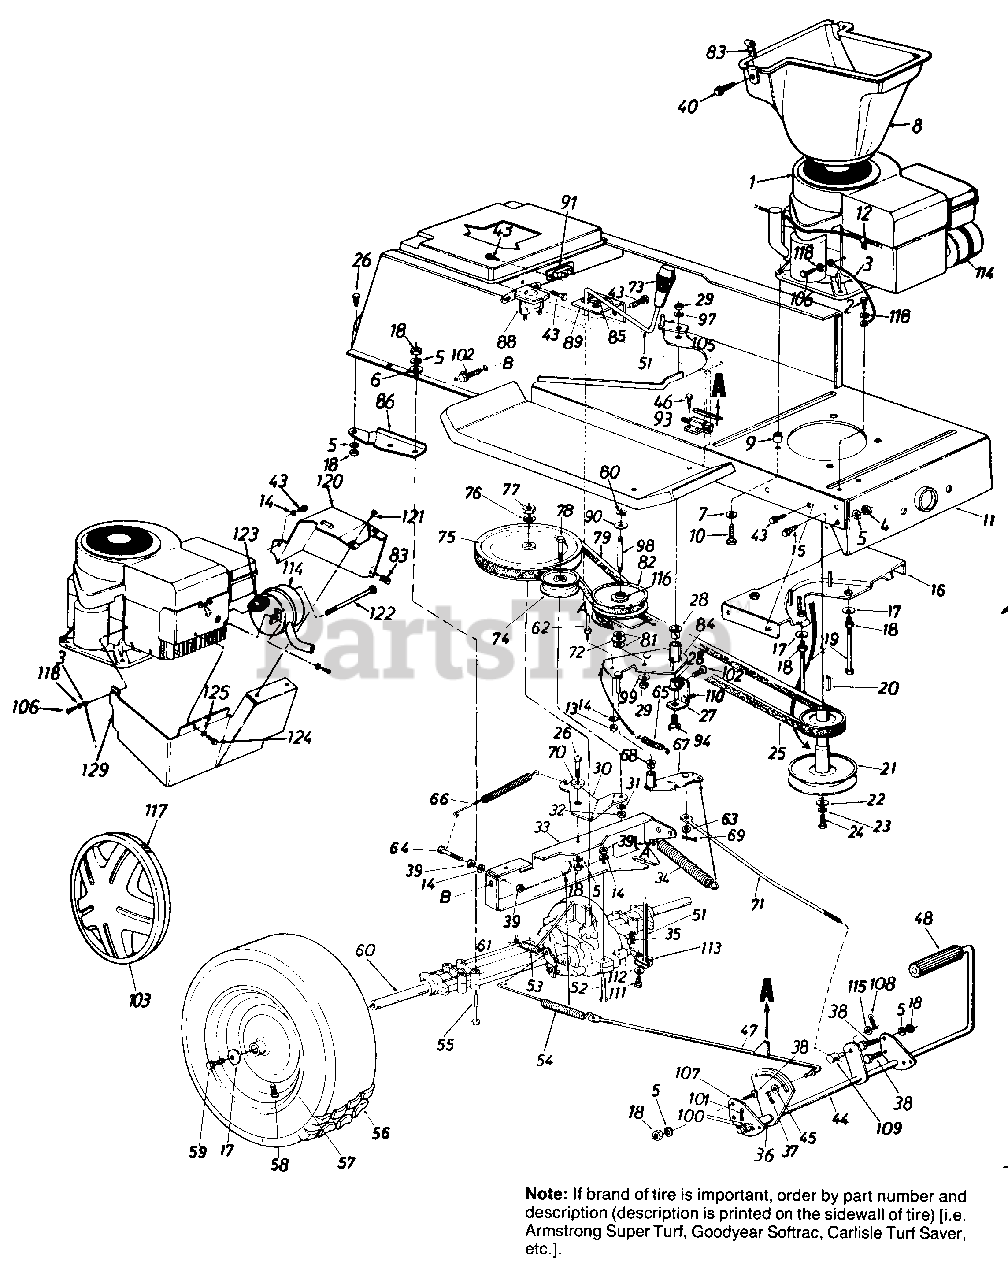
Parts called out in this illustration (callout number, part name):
1	Engine
2	Hex Wash. AB-Tap Scr. 5/16" x .75"
3	Electric Ground Wire
4	Hex Nut 5/16-24 Thd.
5	L-Wash. 5/16" I.D.
6	Fl-Wash. .33" I.D. x .63"
7	Fl-Wash. .406" I.D. x 1.25"
8	Air Duct
9	Spacer
10	Hex L-Wash Tap Scr. 3/8-16
11	Lower Frame Ass'y.
12	Speed Clip
13	Hex Nut 1/4-20 Thd.
14	L-Wash. 1/4" I.D.
15	Rib Neck Bolt 5/16-24 x .84" Lg
16	Belt Guard Brkt. Ass'y.
17	Bell-Wash. .345" I.D. x .88"
18	Hex Nut 5/16-18 Thd.
19	Hex Bolt 5/16-18 x 4.0"
20	Sq. Key 1/4" x 1/4" x 2.00"
21	Engine Pulley
22	Fl-Wash. 7/16" I.D. x 1.25"
23	L-Wash. 7/16" I.D.
24	Hex Bolt 7/16-20 x 1.50" Lg.
25	Variable-Speed Belt
26	Hex Bolt 5/16-18 x .75" Lg.
27	Bearing Shaft Bracket Ass'y.
28	Flanged Nyliner Brg. 5/8" I.D. x .88" Lg.
29	Hex Nut 3/8-24 Thd.
31	L-Wash. 3/8" I.D.
32	Hex Nut 3/8-24 Thd.
33	Transaxle Support Brkt.
34	Ext. Spring .94" O.D. x 7.58"
35	Inter. Cott-Pin
36	Spacer.63" I.D.
37	Cotter Pin 3/32" Dia. x .75"
38	Hex Wash. Hd. Tap Scr. 5/16-18 x .87" Lg.
39	Hex Nut 1/4-28 Thd.
40	Truss Mach. Scr. #10-24 x .5" Lg.
43	Hex Wash. Hd. S-Tap Scr. 1/4-20 x .50" Lg.
44	Clutch/Brake Pedal Ass'y.
45	Fl-Wash.
46	Truss Mach. Scr. B-Tap Scr. #10 x .5" Lg.
47	Brake Rod Ass'y.
48	Foot Pad
51	Shift Lever Ass'y.
52	Hex Bolt 1/4-28 x 1.75" Lg.
53	Ext. Spring .38" O.D. x 2.5"
54	Ext. Spring .59" O.D. x 7.08"
55	Hex Bolt 5/16-18 x 2.75"
57	Wheel Rim Only
58	Air Valve
59	Hex Bolt 5/16-24 x .75" Lg.
60	Transaxle Complete
61	Brake Return Spring Anchor
62	Belt Guard Pin 1/4-20 Thd.
63	Fl-Wash. .34" I.D. x .68" O.D.
64	Hex Bolt 1/4-28 x 1.25" Lg.
65	Ext. Spring
66	Ext. Spring .62" O.D. x 6.12"
68	Flanged Bearing
69	Cotter Pin 3/32" Dia.
70	Shoulder Spacer .27" Lg.
71	Speed Control Link
72	Truss Bearing .56 Dia. x 1 .25"
73	Shift Knob
74	Fl-Idler Pulley 3.25" x .75"
75	1/2 " "V"-Pulley
76	L-Wash. 1/2" I.D.
77	Hex Jam Nut 1/2-20 Thd.
78	Hex Bolt 3/8-24 x 1.75" Lg.
79	Variable Speed Belt
80	Snap Ring .56" Dia.
81	Fl-Wash.
82	Variable Speed Pulley Ass'y. 5" O.D.
83	Speed Nut #10-24 Thd.
90	Teflon Washer .565" I.D.
91	Circuit Breaker
93	Safety Switch (Clutch)
94	Shld. Bolt 3/8-24 x 3.12" Lg.
97	Bell-Wash. .38" I.D. x .88"
98	Shaft .56" Dia. x 3.875" Lg.
99	Bell-Wash. .39" I.D. x 1.12"
100	Fl-Wash. .64" I.D. x .94"
101	Cotter Pin 3/32" Dia. x 1.0"
102	Hex Wash. Hd. Scr. 5/16-18 x.62" Lg.
103	Hub Cap
105	Belt Guard
106	Truss Mach. Scr. 5/16-18 x .75" Lg.
107	Pedal Bracket
108	Cotter Pin 3/32" Dia. x .75"
109	Ferrule
110	Hex Bolt 5/16-18 x 1.0" Lg. (Grade 5)
111	Hex Bolt 1/4-28 x .50" Lg.
112	Bell-Wash. .265" I.D. x .75"
113	Shift Lever Link Ass'y.
114	Muffler
115	Fl-Wash. .385" I.D. x .62"
116	Needle Brgs.
117	Spring Clip
118	External L-Wash. 5/16" I.D.
120	Muffler Heat Shield L.H.
121	Hex Wash. Hd. AB-Tap Scr. #10 x .5" Lg.
122	Shld. Bolt 7/16" Dia. x 3-5/8" Lg.
123	Gasket
124	Hex Bolt 1/4-20 x 3/8" Lg.
125	Spr. Wash. .265" I.D. x .562"
129	Muffler Heat Shield Front
